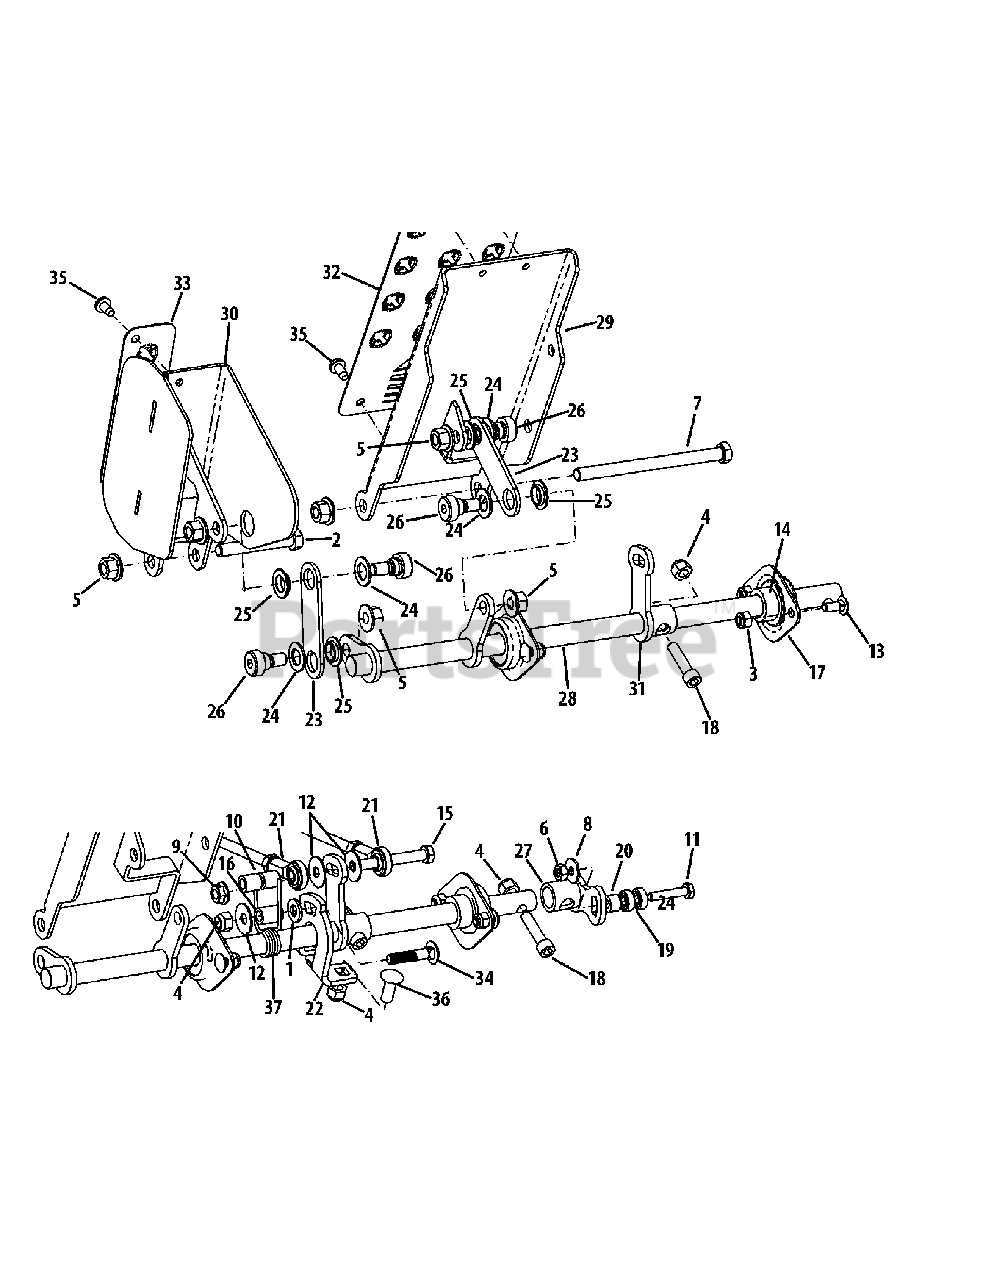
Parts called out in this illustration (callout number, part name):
1	Washer, .344 x .688 x .063
2	Hex Screw, 3/8-16 x 2.50
3	Nut, 1/4-20
4	Nut, 5/16-18
5	Flange Counter Lock Nut, 3/8-16
6	Counter Lock Nut, 1/4-20
7	Hex Screw, 3/8-16 x 5.00
8	Bell Washer, .265 x .75 x .062
9	Flange Counter Lock Nut, 5/16-18
10	Spacer, .315 x .500 x .520
11	Hex Screw, 1/4-20 x 1.25
12	Bell Washer, .325 x .930 x .045
13	Carriage Bolt, 1/4-20 x .620
14	Shaft Collar, .625 x 1.00 x .438
15	Hex Screw, 5/16-18 x 2.50
16	Spacer, .315 x .500 x .699
17	Flange Bearing
18	Screw, 5/16-18 x 1.25
19	Ball Bearing, .25 x .625 x .196
20	Spacer, .256 x .500 x .330
21	Speed Control Link Assembly
23	Pedal Control Link
24	Washer, .51 x .88 x .06
25	Flange Bearing, .502 x .875 x .180
26	Shoulder Bolt, 3/8-16 x .50 x .25
27	Lockout Hub Assembly
28	Pedal Bellcrank Assembly
29	Forward Pedal Assembly
30	Reverse Pedal Assembly
31	Control Arm Assembly
32	Forward Pedal Grip
33	Reverse Pedal Grip
34	Carriage Bolt, 5/16-18 x 1.50
35	Screw, 1/4-20 x .5
36	Carriage Bolt, 5/16-18 x .88
37	Torsion Spring, .66 x .56
